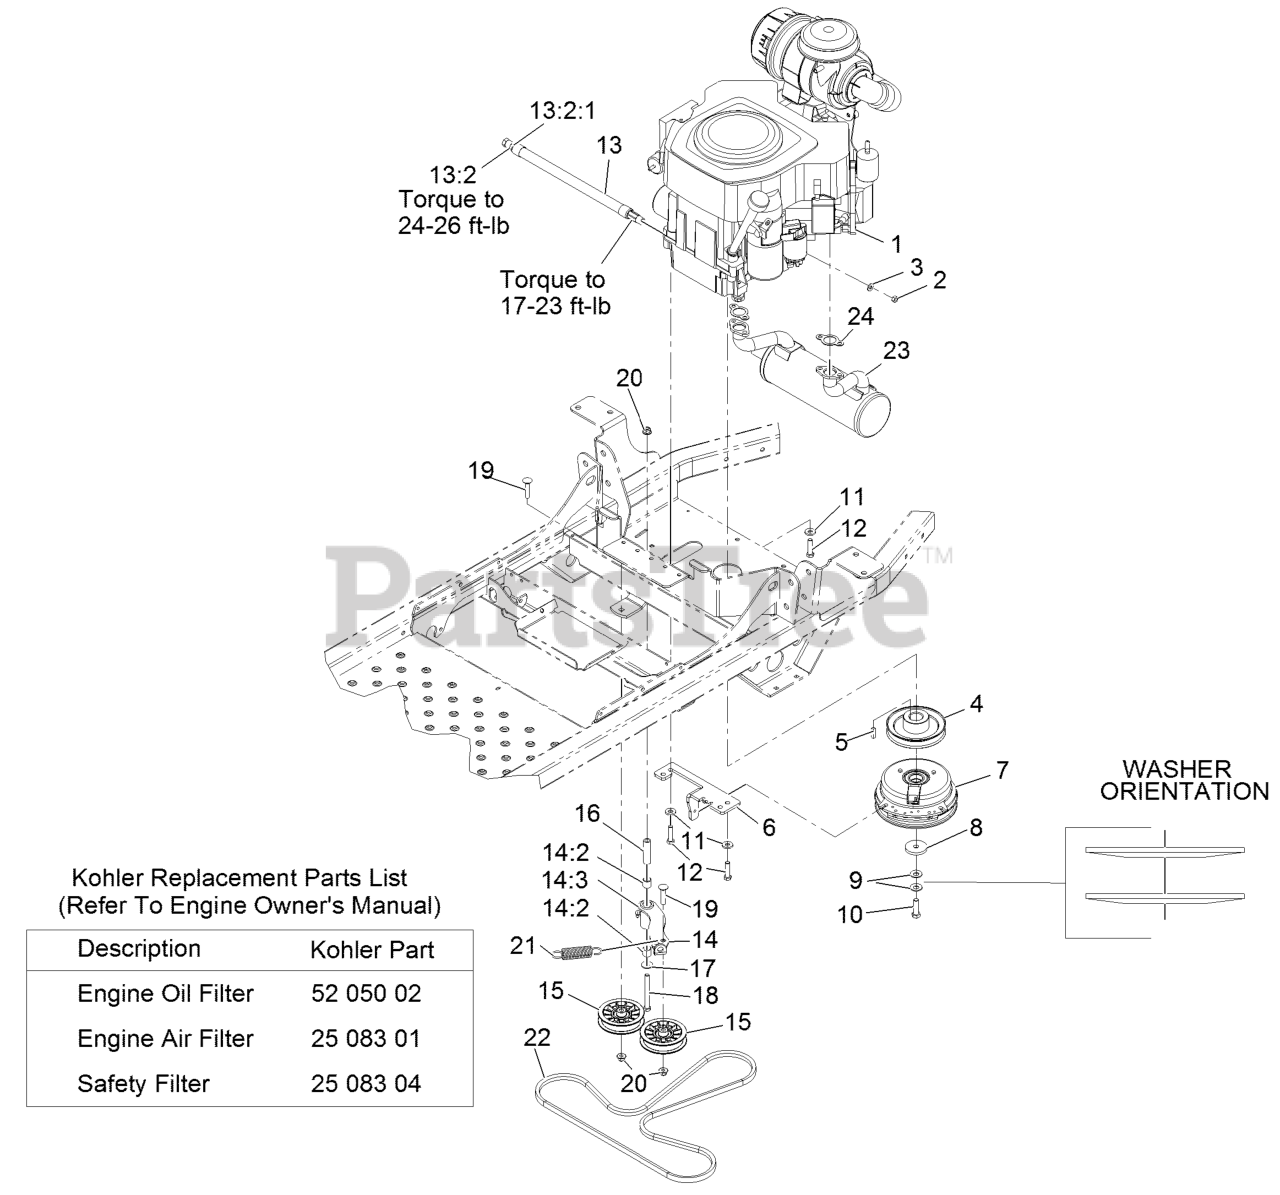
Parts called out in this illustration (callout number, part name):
1	Engine-Kohler
2	NUT-HEX
3	WASHER-FLAT
4	SHEAVE-PUMP, DRIVE
6	ANCHOR-CLUTCH
8	WASHER-CLUTCH
9	WASHER-SPRING
10	SCREW-HH 7/16-20 X 1 1/2 W/LOCTITE
11	WASHER-BELLEVILLE
12	SCREW-HWH
13	OIL DRAIN HOSE ASM
13:2	PLUG-HH
13:2:1	O-RING
14:2	SLEEVE-BEARING
14:3	FITTING-GREASE, 90 DEG
15	PULLEY-FLAT IDLER
16	BUSHING-PIVOT, IDLER
17	WASHER-FLAT
18	SCREW-CARR
19	SCREW-CARR
20	NUT-HF, NI
21	SPRING-EXTENSION
22	V-BELT
23	MUFFLER-KOHLER TWIN
24	GASKET-EXHAUST
